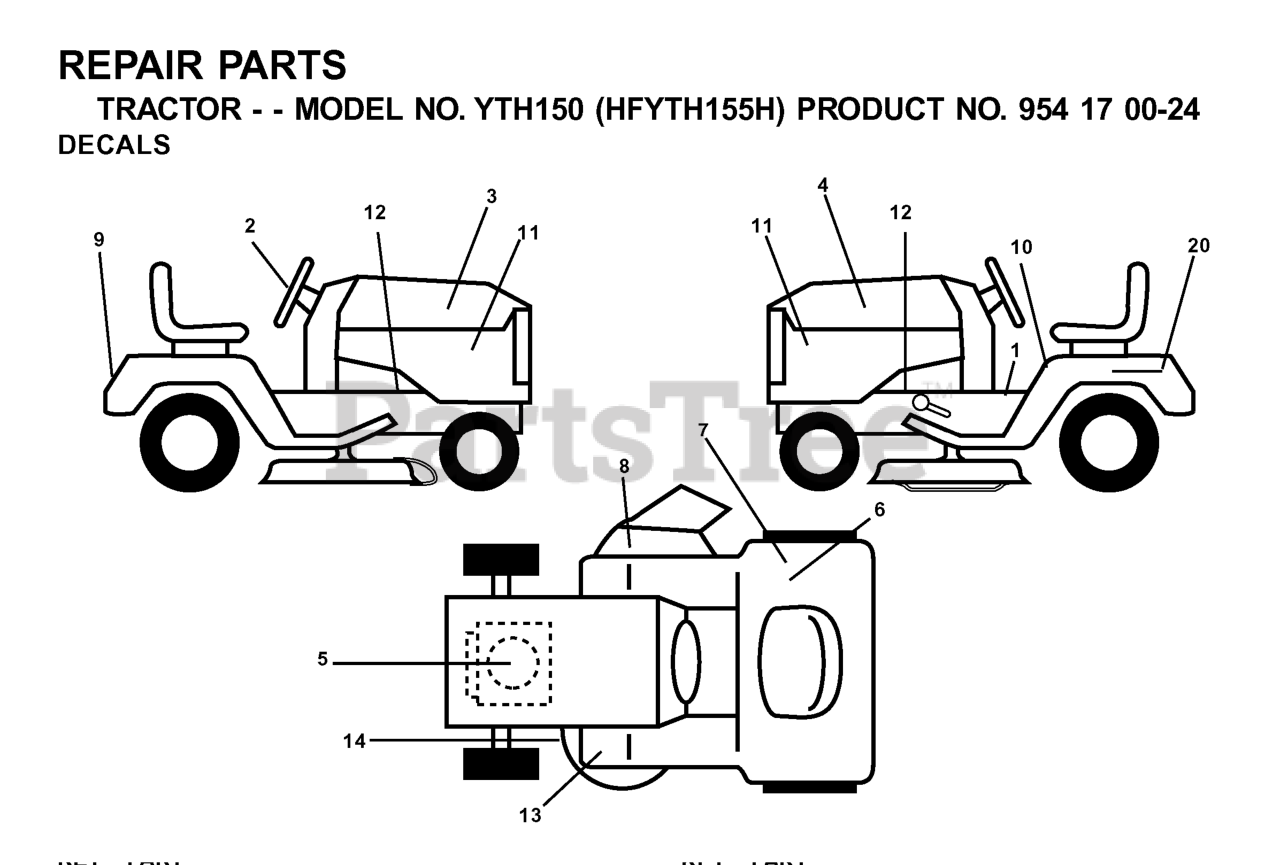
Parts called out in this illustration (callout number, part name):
1	DECAL PARK BRAKE
2	DECAL.WHEEL.STEERING.HUSQ.PERM
3	DECAL, HOOD RH YTH150
4	DECAL, HOOD LH YTH150
6	DECAL CERTIFICATION
7	DECAL EUROPE STANDARD CE
8	DECAL MOWER CUT/FINGER
9	DECAL FENDER HUSQ
10	DECAL READ OWNER'S MAN SYMS
11	DECAL PNL SIDE
13	DECAL
14	DECAL V BELT SCHEMATIC
20	DECAL BTRY SYMBOLS
